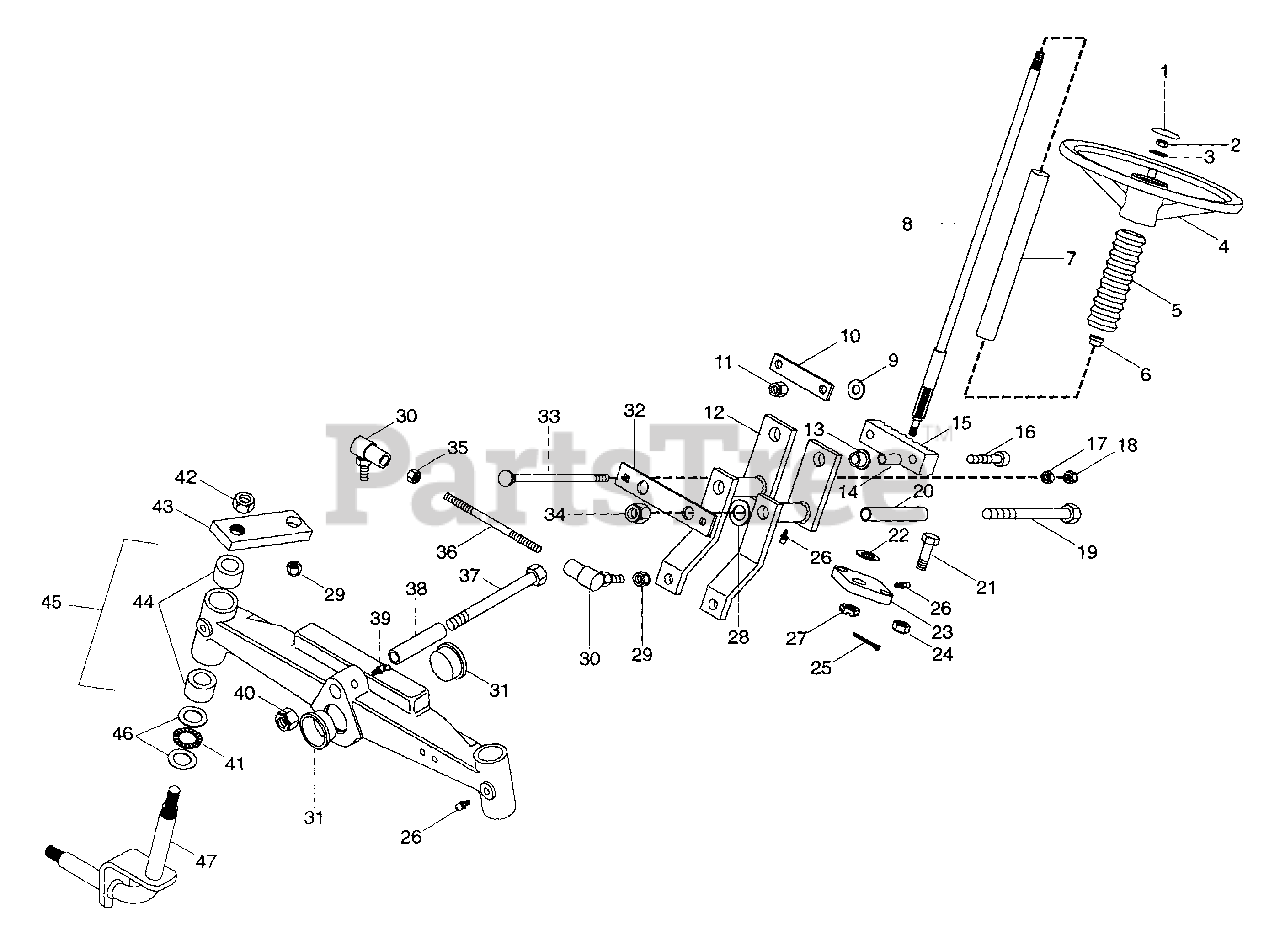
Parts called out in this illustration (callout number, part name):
1	Steering Wheel Cap
2	Nut-Jam .625-11
3	Washer-Flat-Steel .656 x 1.312 x .095
4	Steering Wheel
5	Steering Column Boot
6	Bushing-Flange .762 x 1.0 x 580 x 1.48
7	Tube, Plastic 1.0 I.D.
8	Weldment, Steering Shaft
9	Washer-Flat-Steel .375 x 1.125 x .065
10	Strap, Rack and Pinion
11	Nut-Locking-Nylon .375-16 Grade 2
12	Weldment, Steering
13	Bushing-Flange .627 x .879 x .469 x 1.120
14	Bushing, Steel .391 x .621 x .676
15	Grade, Rack
16	Screw-Cap .38-16 x 2
17	Nut-Hex .312-18 Grade 2
18	Nut-Locking-Nylon .312-18 Grade 2
19	Bolt-Hex .50-13 x 6.00
20	Sleeve, Pivot
21	Bolt-Hex .44-14 x 1.50
22	Washer-Thrust .507 x .917 x .031
23	Support, Steering Shaft
24	Nut-Locking-Hex .44-14
25	Pin-Cotter .09 x 1.0
26	Fitting-Lube .25-28 x .256
27	Nut-Hex-Slotted .500-13
28	Bearing-N-Thrust .752 x 1.24 x .093
29	Nut-Locking-Nylon .375-24 Grade 2
30	Joint, Steering Ball
31	Cap, Front Axle
32	Plate, Adjustment
33	Bolt-Round Head Square Neck .31-18 x 5.50 Grade 2
34	Nut-Locking-Nylon .50-13 Grade 5
35	Nut-Hex .375-24 Grade 2
36	Rod, Steering
37	Bolt-Hex .75-10 x 4.50
38	Tube, Axle Pivot
39	Fitting, Lube 45 Deg
40	Nut-Locking-Nylon .75-10 Grade 2
41	Bearing-Thrust .875 x 1.427 x .078
42	Nut-Hex .625-11 Grade 2
43	Arm, Tie Rod Axle
44	Bushing-Sleeve .866 x 1.004 x 1.000
45	Axle, Steering
46	Washer-Thrust .877 x 1.427 x .032
47	Weldment, King Pin
